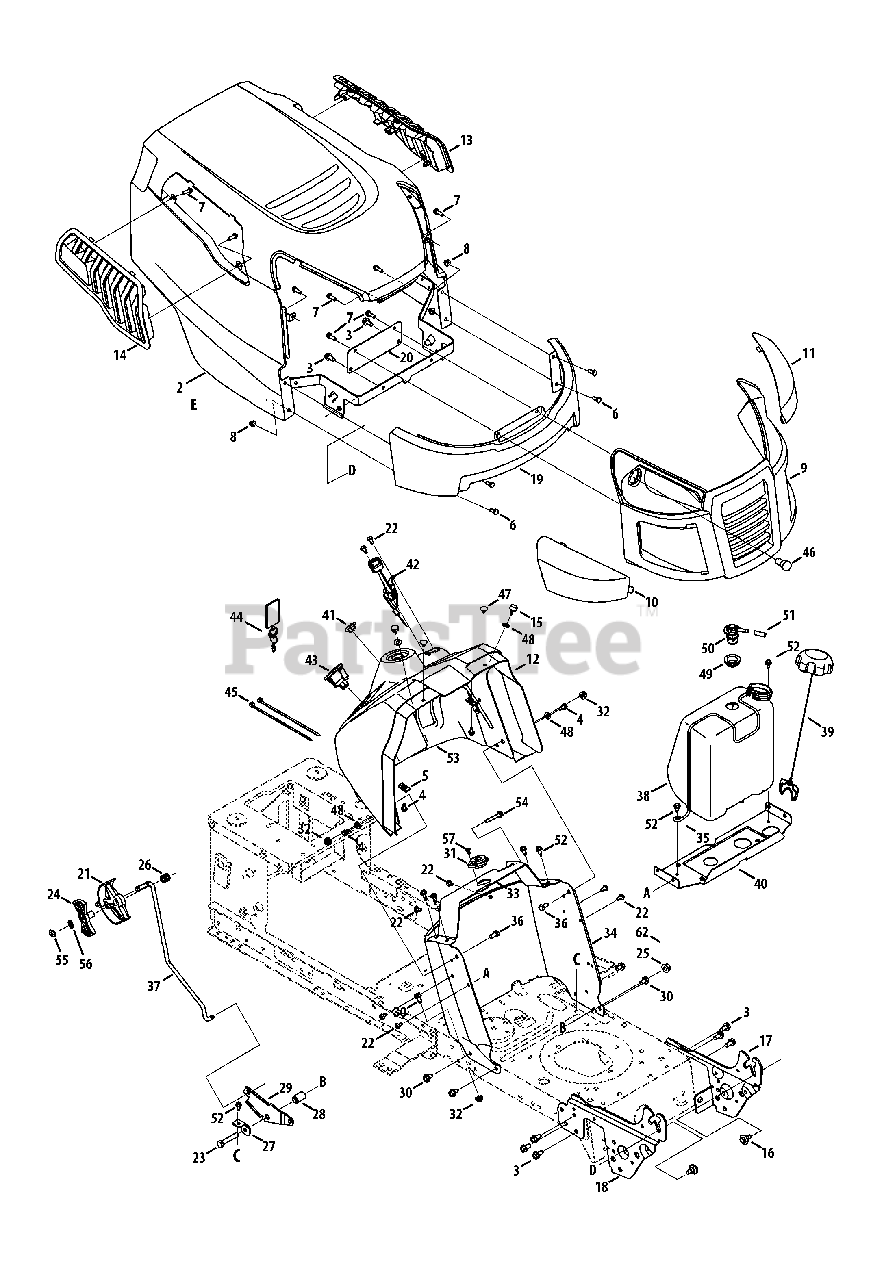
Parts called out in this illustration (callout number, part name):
1	Bulb Socket
2	Hood Assembly
3	Screw, 5/16-18 x .750
4	Hex Washer Screw, 1/4-20 x .500
5	Tin Clip Nut, 1/4-20
6	Hex Screw, 1/4-20 x .620
7	Screw, 1/4 x .750
8	Nut, Hex Flange Insert Lock, 1/4-20
10	Headlight Lens, RH
11	Headlight Lens, LH
12	Dash Collar
13	Hood Scoop, LH
14	Hood Scoop, RH
15	Bumper
16	Shoulder Screw, 5/16-18
17	Left Support Pivot Bracket
18	Right Support Pivot Bracket
19	Lower Grill
20	Lower Grill Bracket
21	Shift Lever
22	Self-Tap Screw, 1/4-20
23	Hex Head Screw, 3/8-16
24	Control Index
25	Nut, Hex Flange Insert Lock, 3/8-16
26	Compression Spring
27	Speed Latch Support Tab
28	Flange Spacer
29	Speed latch Bracket No RMC
30	Self-Tap Screw, 5/16-18
31	Steering Column Bearing
32	Nut, Hex Flange Lock, 5/16-18
33	Steering Support Bracket
34	Dash
35	Fuel Tank Support Rod
36	Hex Head Screw, 5/16-18
37	Control Rod
38	Fuel Tank
39	Fuel Cap
40	Gas Tank Support Bracket
41	Choke Plug
42	Throttle/Choke Assembly
43	Key Switch Module
44	Key Assembly
45	Cable Tie
46	Headlight Bulb
47	Ratchet Clip, .250 x .500
48	Flat Washer, .25 x .630 x .0515
49	Rubber Grommet
50	Fuel Rollover Valve
51	Vent Hose
52	Hex Washer Screw, 1/4-20 x .625
53	Upper Dash
54	Hex Flange Bolt
55	Top Lock Weldnut
56	Lock Washer
57	Screw, #10
